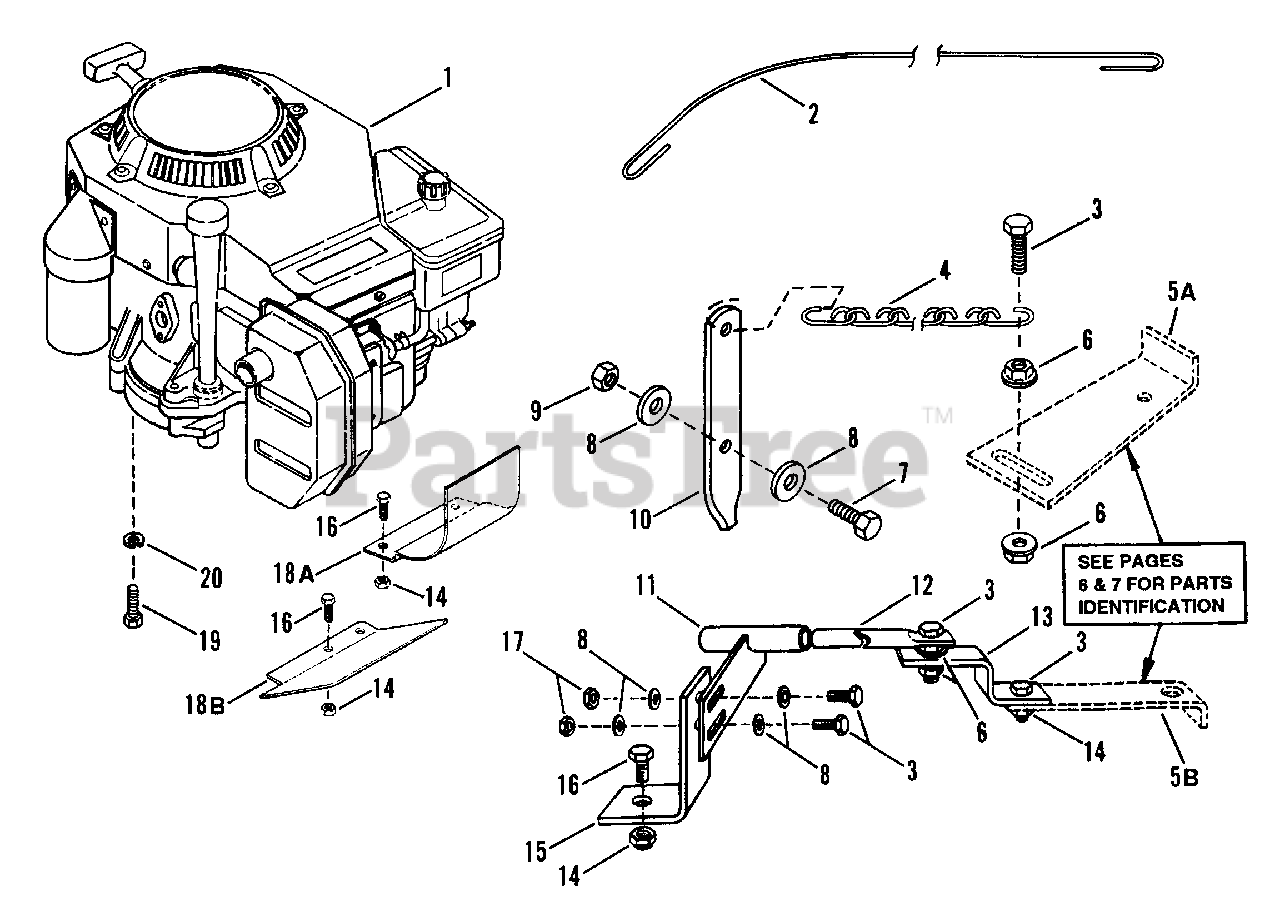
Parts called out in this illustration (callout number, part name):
2	ROD, Reverse
3	BOLT, 1/4-20 X 1" GD5 CZ
4	CHAIN, Reverse
5A	ARM, Reverse
5B	ARM, Reverse
6	NUT, 1/4-20 Hex Flange Lock
7	SCREW, M6-1 x 14mm Hex Cap
8	WASHER, 1/4 Flat
9	NUT, M6-1mm Hex
10	LEVER, Reverse
11	WELDMENT, Guide
12	ROD, Reverse
13	STRAP, Reverse
14	NUT, 5/16-18 HEX NYLON LOCK
15	WELDMENT, Support
16	SCREW, 5/16-18 x 3/4" Hex Cap
17	NUT, 1/4-20 Hex Lock
18A	SHIELD, Heat
18B	SHIELD, Heat
19	BOLT, M8-1.25 X 25MM GD8.8
20	WASHER, 5/16 Split Lock
